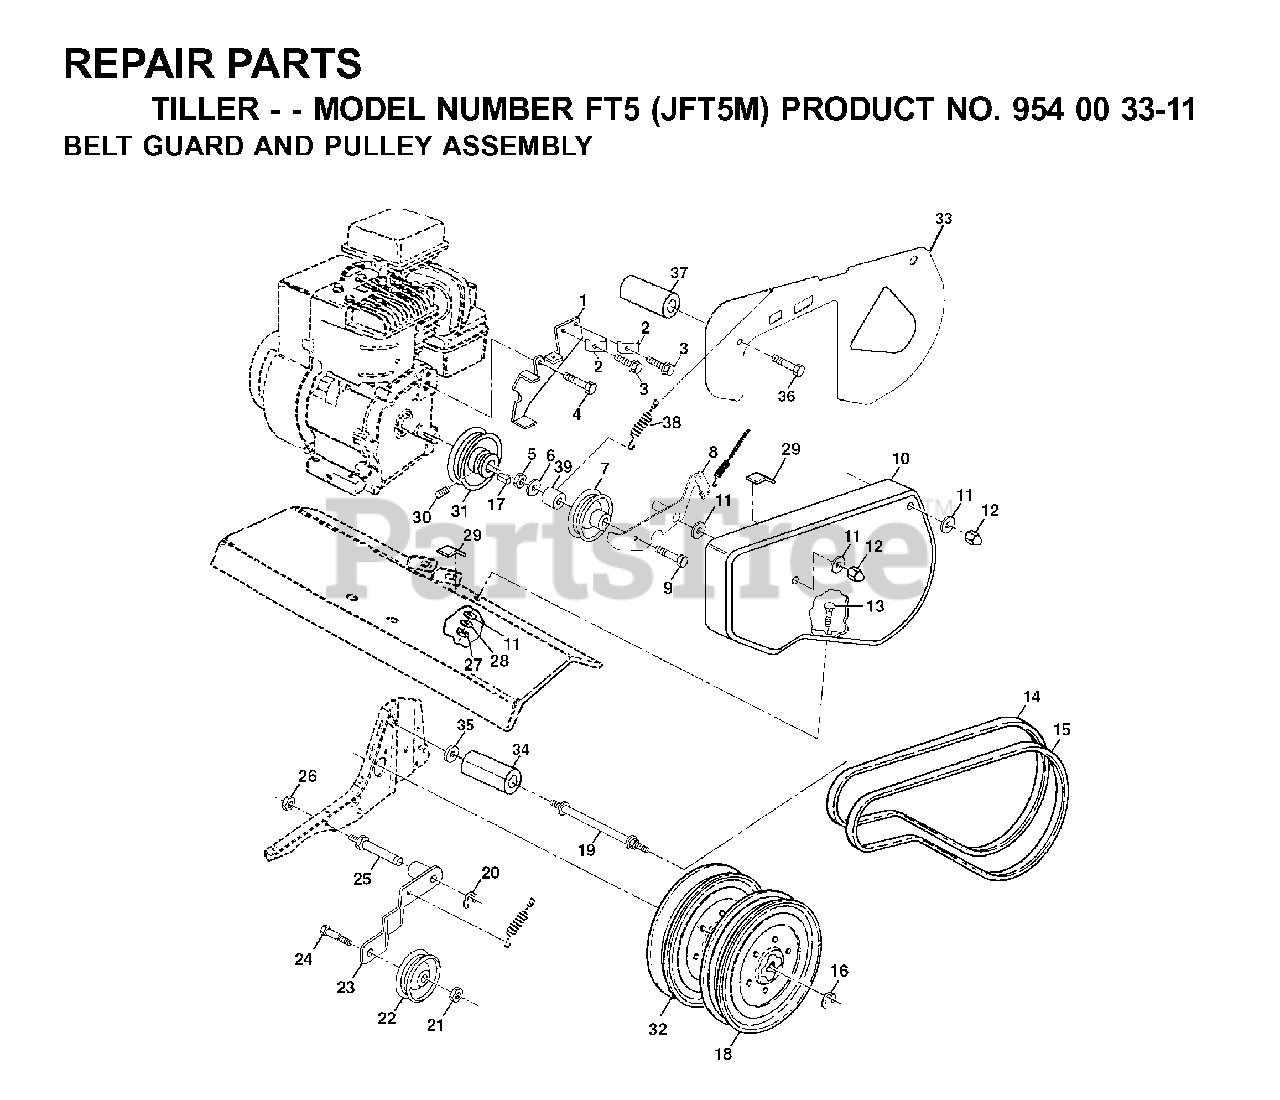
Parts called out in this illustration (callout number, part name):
2	CONDUIT CLIP T
3	TAPPING SCREW
7	PULLEY
8	ARM
9	BOLT
11	WASHER
12	CAP
16	RETAINING RING LT
18	SHEAVE,TRANS."D"
20	KLIP RING TI
21	NUT
22	PULLEY, IDLER
25	SHAFT.IDLER.TILLER
26	JAM NUT TI
27	NUT
28	LOCKWASHER
29	PAD IDLER TI
32	SHEAVE.TRANS
38	SPRING.EXTENSION
